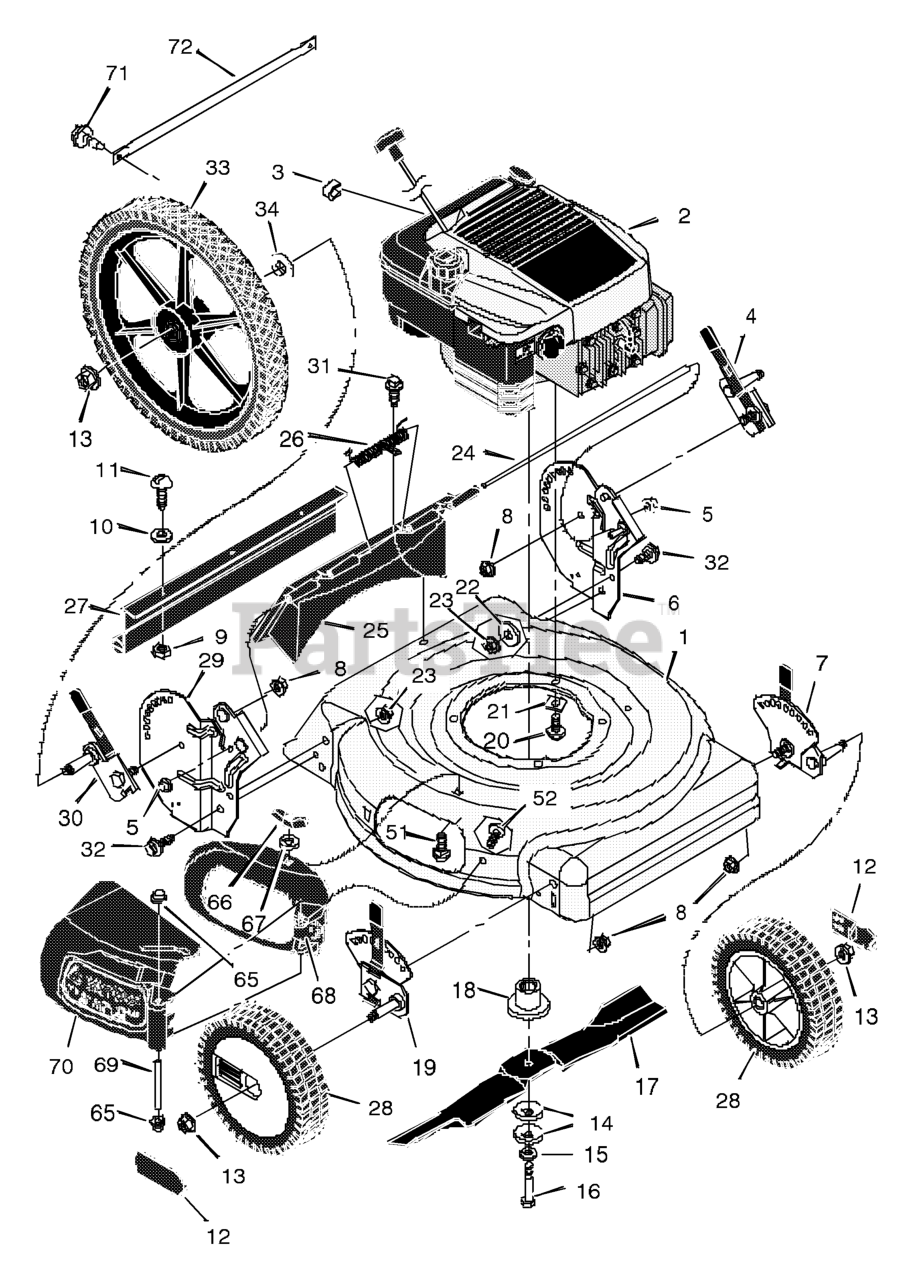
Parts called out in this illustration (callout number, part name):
1	Housing
2	Engine *
3	Stop, Rope (Recoil - Start)
4	Adjuster, Left Height
5	Push On Cap
6	Bracket, Left Handle
7	Adjuster, Left Front Height
8	Nut, Flange
9	Nut, Hex
12	Hub Cap
13	Nut, Flange
14	Washer, Belleville
18	Adapter, Blade
19	Adjuster, Right Front Height
20	Bolt, Engine
21	Support, Engine
22	Washer
23	Nut, Flange
24	Rod, Pivot
25	Door, Rear
27	Guard, Rear
28	Wheel
29	Bracket, Right Handle
30	Adjuster, Right Height
32	Bolt
33	Wheel, Rear
51	Bolt, Carriage
65	Push On Cap
66	Wingnut
67	Retainer, Push
69	Pin, Pivot
70	Deflector, Chute
